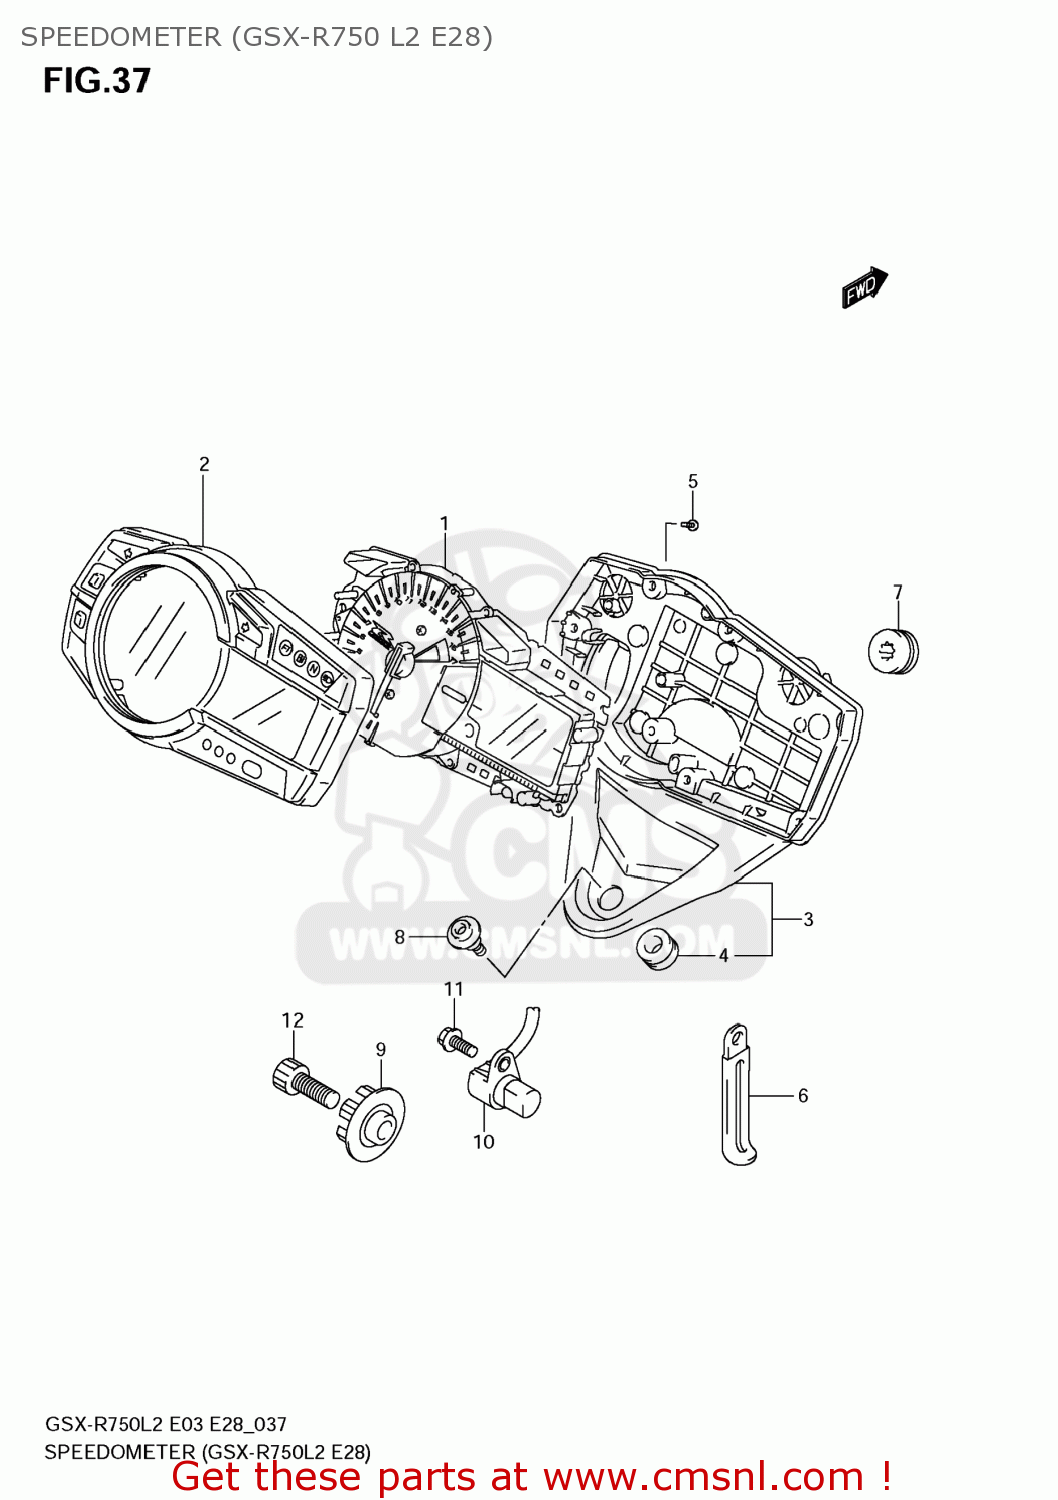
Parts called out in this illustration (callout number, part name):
1	SPEEDOMETER
2	CASE ASSY,UPR
3	LWR CASE ASSY
4	CUSHION,METER
5	SCREW(3X16)
6	CLAMP(L:45)
7	CUSHION
8	SCREW,SPEEDOMETER
9	ROTOR,SPEED
10	SENSOR,SPEED
11	BOLT
12	BOLT
